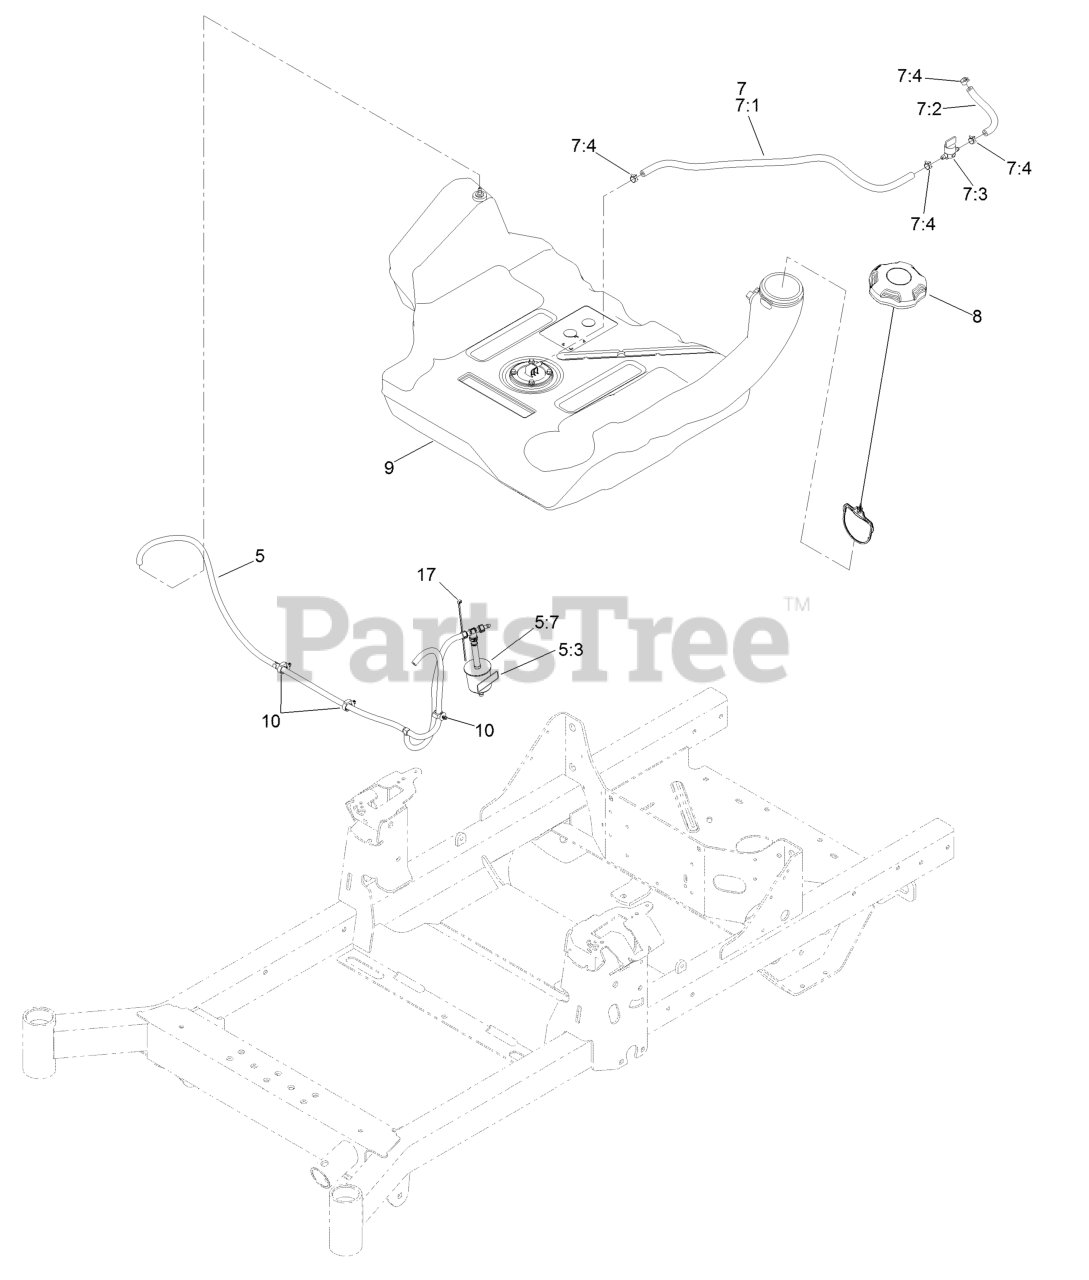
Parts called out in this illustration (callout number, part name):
5	Vent Hose ASM
5:3	Decal-Filter, Emissions
5:7	Filter-Fuel
7	Fuel Hose ASM
7:1	Hose-Fuel
7:2	Hose-Fuel
7:3	Valve-Fuel
7:4	Clamp-Hose
8	Cap-Fuel
9	Tank-Fuel
17	Tie-Cable
